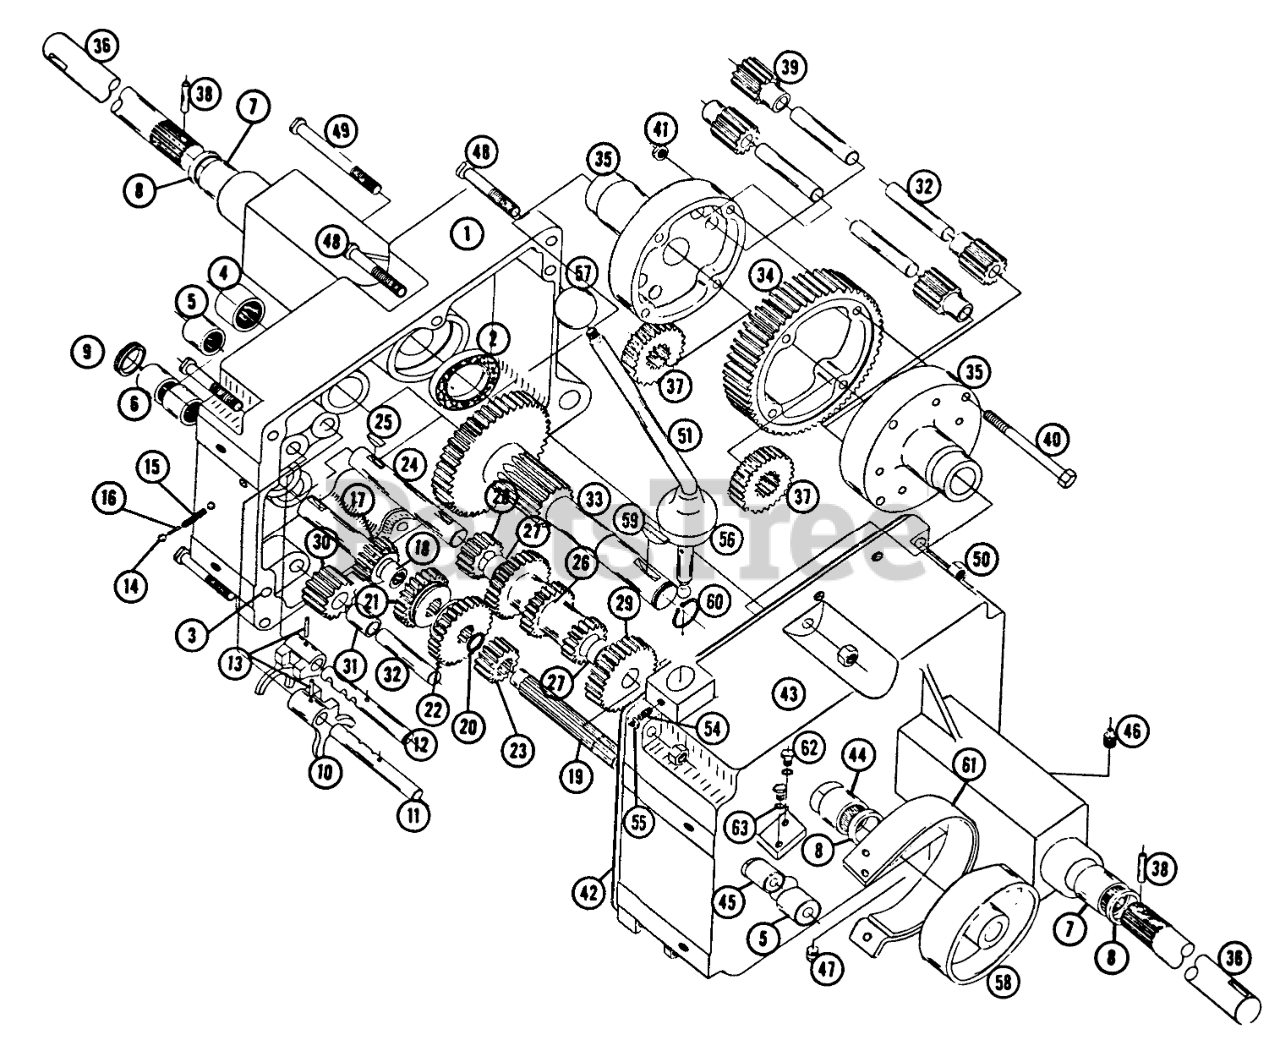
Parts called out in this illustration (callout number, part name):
3	PIN-DOWEL
4	BEARING-NEEDLE
5	BEARING-NEEDLE
7	BEARING-NEEDLE
10	FORK-SHIFT
11	RAIL-SHIFT
12	RAIL-REAR SHIFT
13	PIN-ROLL
14	BALL-DETENT
16	PIN-SHIFT
18	BEARING-NEEDLE
23	GEAR
25	Key
27	BUSHING-BRONZE
29	GEAR-CLUSTER SHAFT
30	GEAR/BUSHING ASM-REVERSE IDLER
31	BUSHING
32	PIN-DIFFERENTIAL
34	SVC BULLT 394
35	DIFFERENTIAL CASE
37	AXLE GEAR
42	GASKET-TRANSMISSION
46	Plug 1/4 Pipe
47	Plug 3/8 Pipe
48	Bolt, 3/8 16 x 2
49	Bolt Hex 3/8-16 x 1
51	Stick-Ship Ass-y.
55	Nut 1/4-20
56	COVER-DUST
59	KEY-WOODRUFF
62	Bolt-1/4-20 x 5/8
63	Lockwasher
